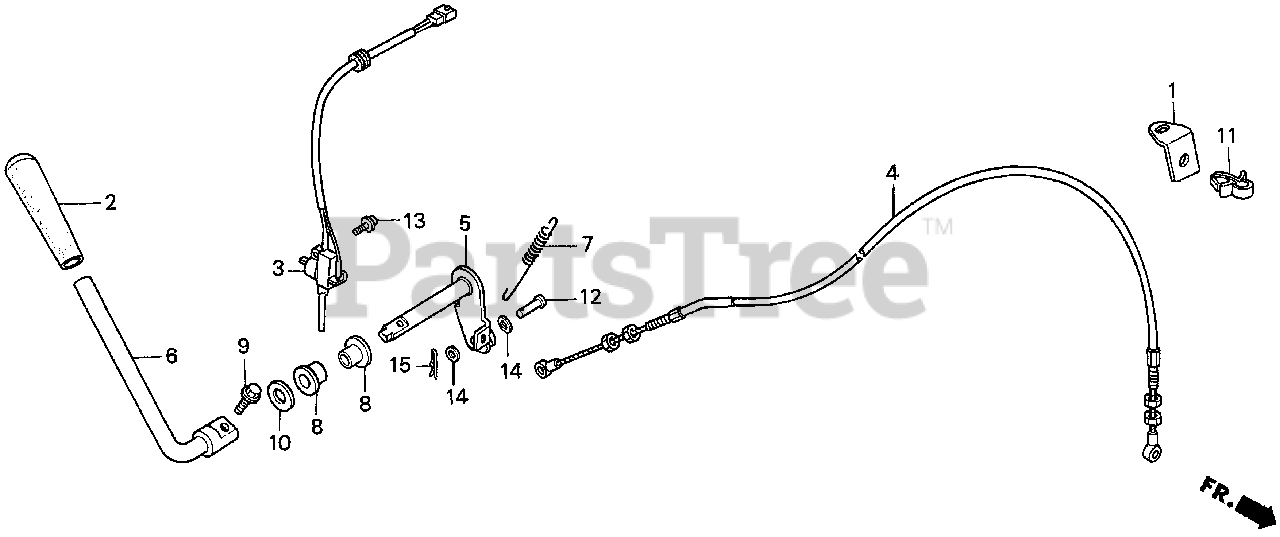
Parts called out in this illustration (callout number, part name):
1	BRACKET, P.T.O. CABLE CLAMP
2	GRIP, P.T.O. CLUTCH LEVER *Y121* (YELLOW)
3	SWITCH ASSY., P.T.O. CLUTCH
4	CABLE, P.T.O. CLUTCH
5	ARM, P.T.O. CLUTCH LEVER
6	LEVER, P.T.O. CLUTCH
7	SPRING, P.T.O. CLUTCH
8	BUSH, P.T.O. CLUTCH ARM
9	BOLT, FLANGE (6X12)
10	WASHER (14MM)
11	CLIP, WIRE HARNESS
12	PIN, AUXILIARY CHANGE LEVER JOINT
13	SCREW-WASHER (4X12)
14	WASHER, PLAIN (6MM)
15	PIN, LOCK (6MM)
